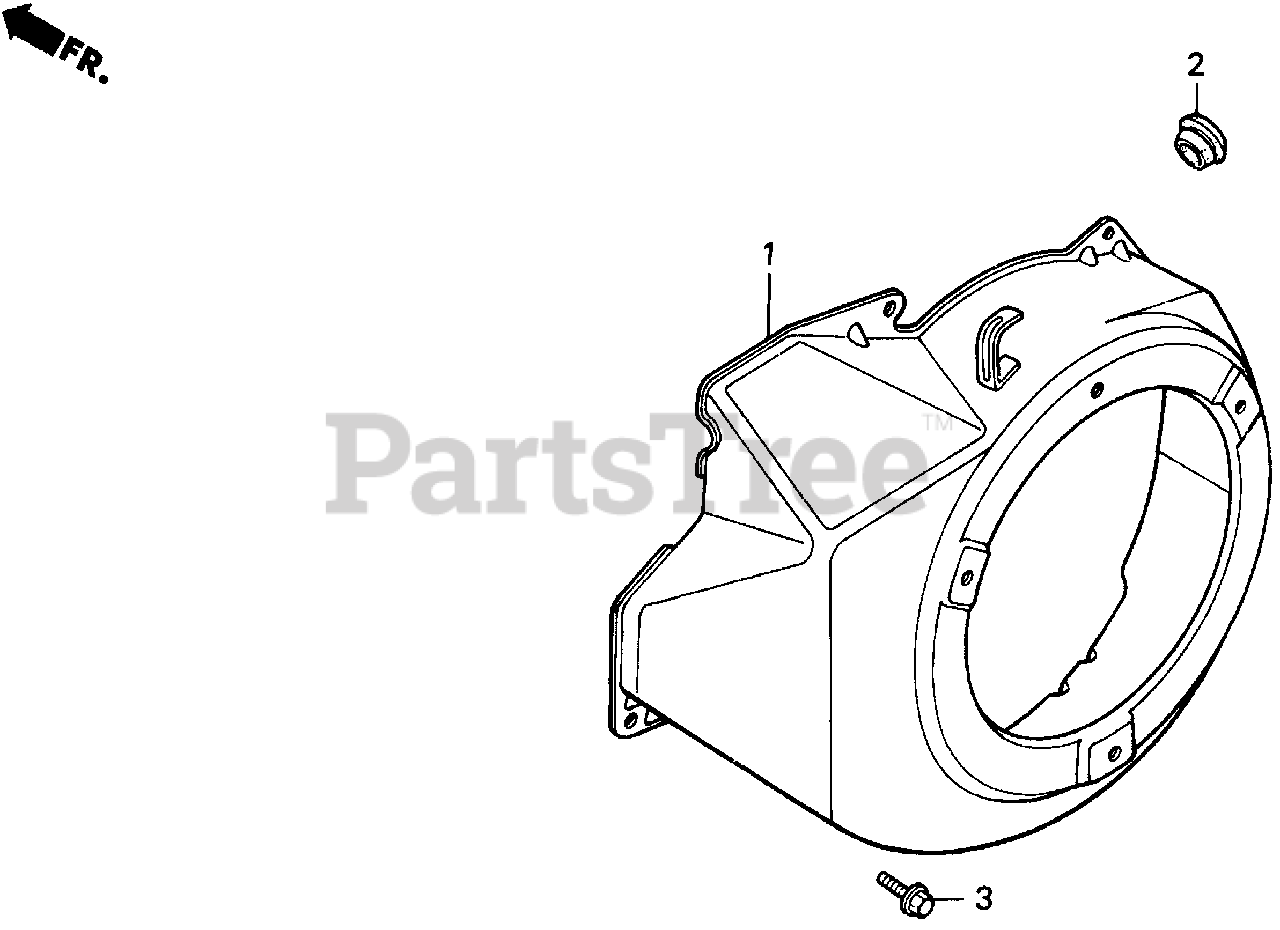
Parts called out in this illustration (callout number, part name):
1	COVER, FAN *R8* (BRIGHT RED)
2	GROMMET, DRAIN HOLE
3	BOLT, FLANGE (6X12) (CT200)
